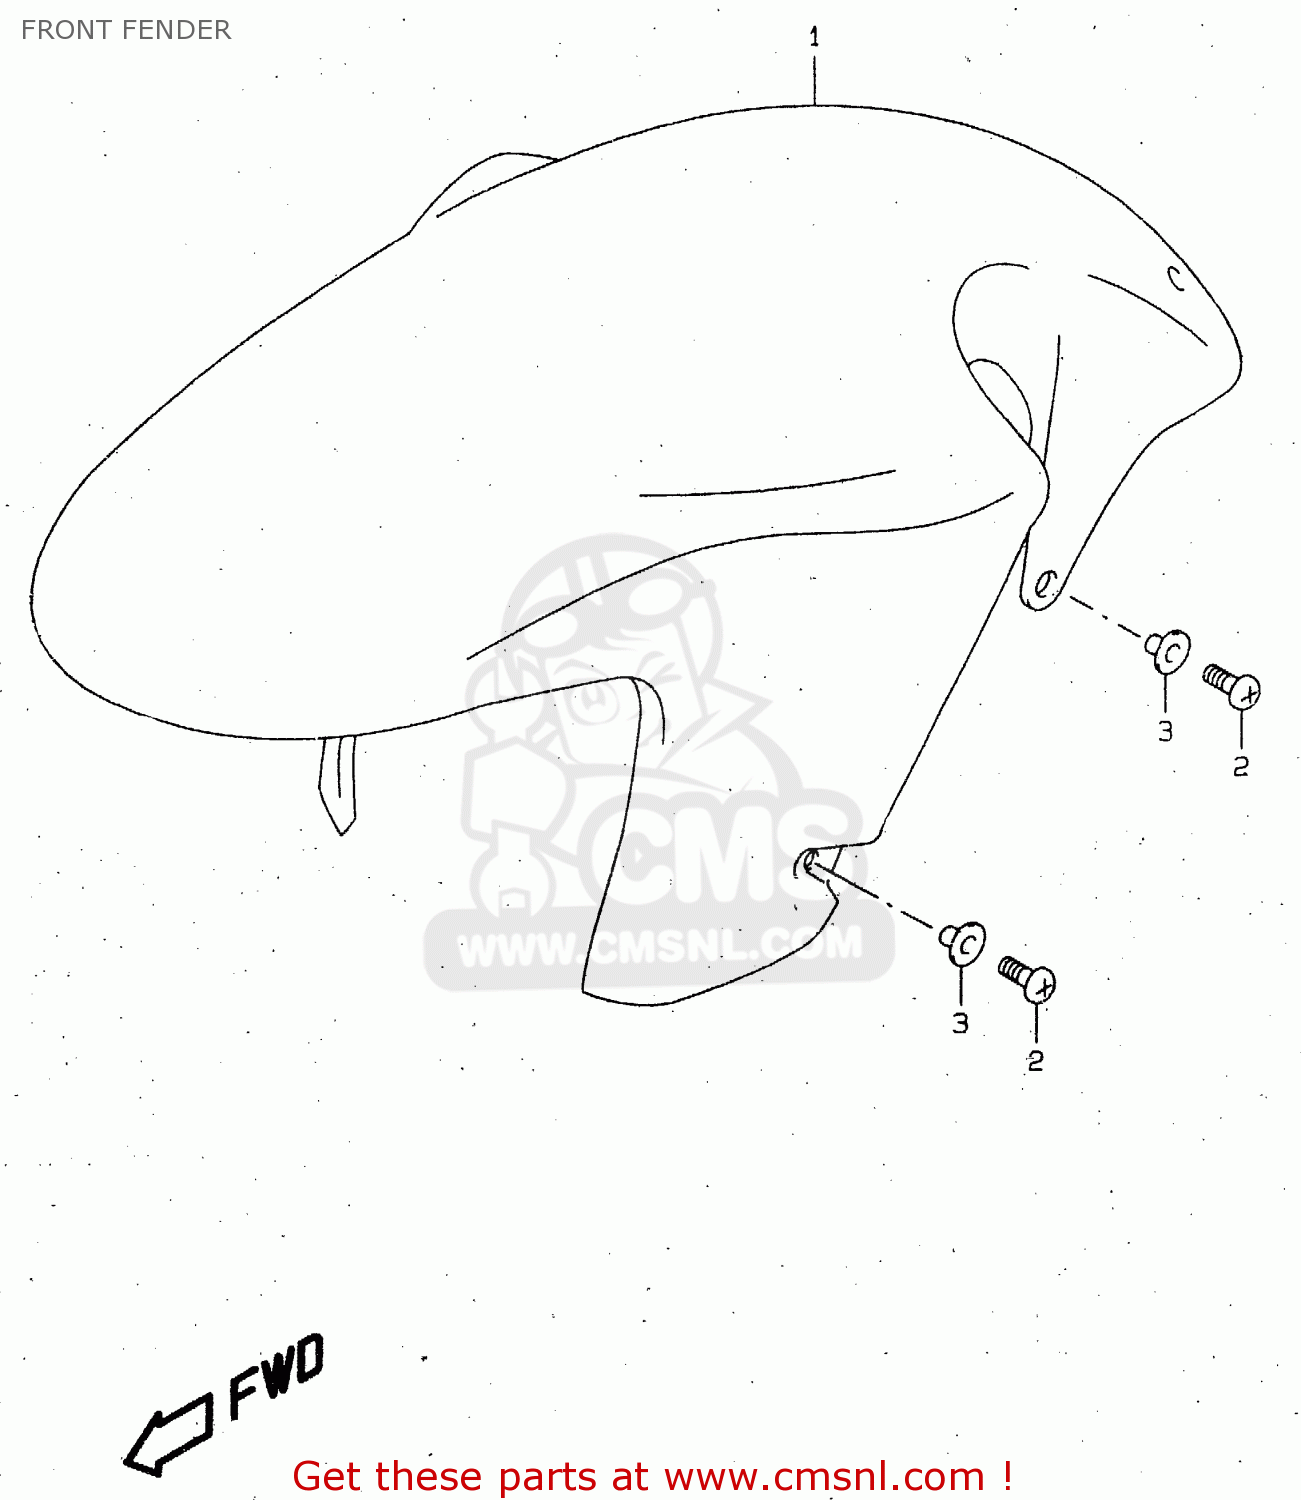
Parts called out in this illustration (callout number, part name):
1	FENDER,FR
2	SCREW(6X16)
3	WASHER(6.3X16X1.5)
